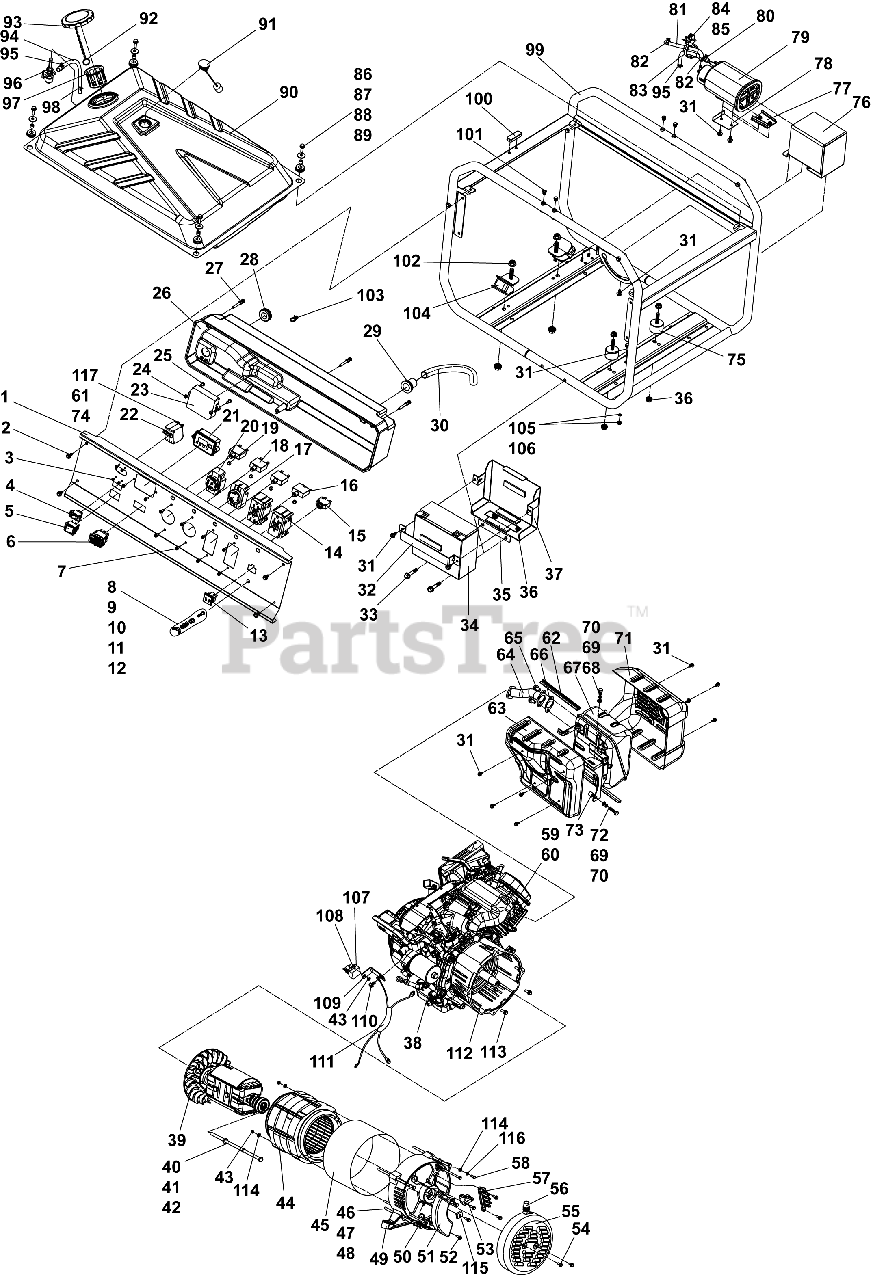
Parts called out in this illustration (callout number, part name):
1	PANEL (PRO5.2)
2	SCREW, BOLT GB5789-M6X12
3	SCREW, M3X6
7	SCREW M4X12
9	WASHER, SPRING GASKET 6
10	WASHER, PLATE GASKET 6
12	SCREW, BOLT M6X25
14	RECEPTACLE, GFCI 20A/125V NEMA 5-20OR
16	BREAKER, CIRCUIT 20A
17	RECEPTACLE, NEMA L5-30R SOCKET
18	BREAKER, CIRCUIT 30A
20	RECEPTACLE, NEMA L14-30R 4P SOCKET
21	METER, MAINTENANCE MINDER
22	BREAKER, CIRCUIT 18.5A (PRO 5.2E)
27	SCREW M5X45
28	GROMMET 16MM
29	GROMMET, POWER CORD SHEATH
30	SLEEVE BRAIDED SLEEVE 1
31	SCREW, BOLT M6X12
38	CH440 E3 KPP
39	ROTOR ASSEMBLY (PRO5.2E)
40	BOLT 5/16-24X222MM
42	WASHER, SPRING
44	STATOR ASSEMBLY
46	WASHER, SPECIAL SPRING 6
47	WASHER, PLATE GASKET 6
48	SCREW BOLT M6X180
49	CAP, BACK COVER
50	SCREW, BOLT M5X205
51	RECTIFIER AVR (PRO5.5E)
52	SCREW, BOLT GB 5787-M5X16
53	BRUSH, CARBON ASSEMBLY
54	SCREW, BOLT M5X10
56	SLEEVE, MOTOR RUBBER SHEATH
57	BOARD ASSEMBLY, PATCH
58	BOLT GB/T 5783-M5X10
59	GASKET, MUFFLER
60	NUT USE 25 086 240-S
61	WASHER, SPRING GB93-4
62	MOUNT, RUBBER GASKET
63	GUARD MUFFLER BACK COVER
64	MANIFOLD, MUFFLER PIPE ASSEMBLY
65	SCREW, BOLT M8X22
68	SCREW, BOLT M8X20
69	WASHER, SPRING 8
70	WASHER, FLAT GASKET 8
71	GUARD, MUFFLER FRONT COVER
72	SCREW, BOLT L35
73	SPACER, MUFFLER BUSHING
74	WASHER, PLATE GASKET GB95-4
75	MOUNT, RUBBER FOOT
77	PLATE, CARBON TANK HOLDER (W/NUT)
78	PLATE, CARBON TANK HOLDER (NONE NUT)
79	CARBON CANISTER
80	CLAMP, FUEL PIPE 5
81	HOSE, FUEL PIPE 2
82	CLAMP, FUEL PIPE 7
83	FUEL HOSE, LOW PERMEATION
84	STRAP, CABLE TIES 7.7X150 8
85	SLEEVE, PVC CASING PIPE 20MM
86	SCREW, BOLT GB 5787-M6X20
87	MOUNT, FLAT GASKET GB/T 5287-6
88	SPACER, INNER RING
89	SPACER, FUEL TANK BUSHING
90	TANK, FUEL
91	GUAGE, FUEL LEVEL ASSEMBLY
92	RETAINER, TANK CAP PULL RING
93	CAP ASSEMBLY - FUEL TANK (EPA)
94	LINE, FUEL (10"-CUT TO LENGTH)
95	CLAMP, FUEL LINE 6
96	VALVE,FUEL SHUT OFF
97	FILTER , FUEL TANK
98	CLAMP, FUEL LINE 1 USE 14 237 01-S
99	FRAME ASSEMBLY (PRO5.2E)
100	DAMPER, HANDLE DAMPING PAD
101	PLUG, END CAP
103	STRAP, CABLE TIES 3.2X120 (WHITE)
104	MOUNT, ENGINE ISO
105	SPACER, FLOWER SHAPED GASKET
113	SCREW BOLT 3/8-16X27MM
114	WASHER, PLATE GT/T 95
116	WASHER, SPRING GB 93-5
117	SCREW GB818-M4X8
